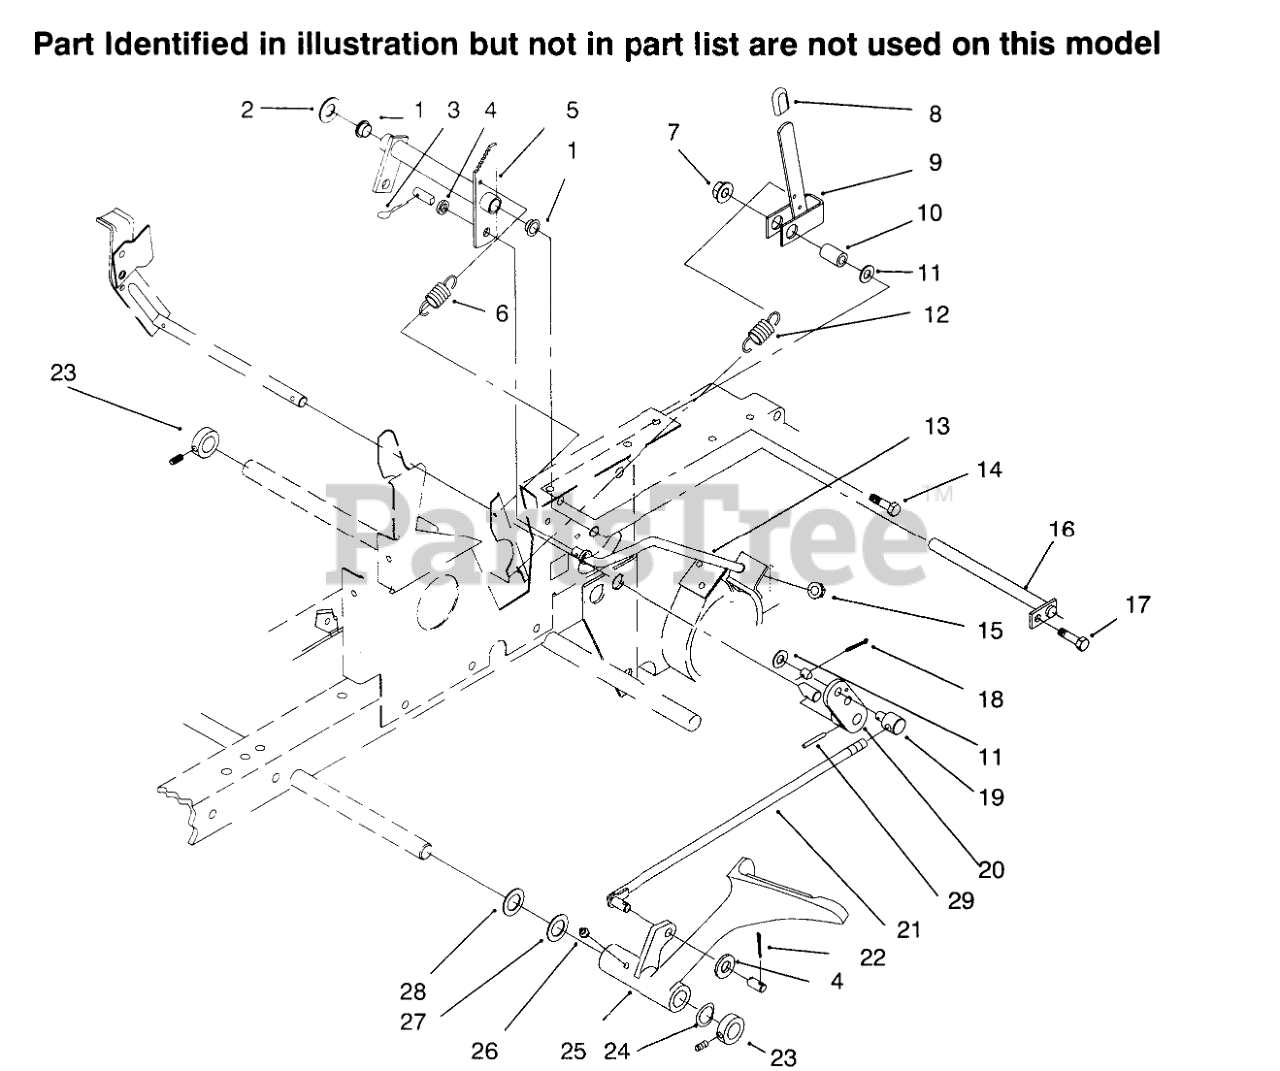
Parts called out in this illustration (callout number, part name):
1	BUSHING-FLANGED
2	WASHER-FLAT
3	PIN-HAIR
4	WASHER-NYLON
5	Bellcrank Assy
6	SPRING-EXTENSION
7	LOCKNUT-FLANGE
8	GRIP
9	ASSY-BRAKE LEVER WAB
10	SPACER
11	WASHER-FLAT
12	SPRING-BRAKE
13	ROD-REAR BRAKE
14	SCREW-HH
15	NUT-LOCK, NI
16	ROD ASM
17	Bolt
18	PIN-COTTER
19	TRUNNION
20	Arm-Clutch Rod
21	ROD AND GUIDE ASM
22	PIN-COTTER
23	COLLAR
24	WASHER-BOWED
25	Pedal-Clutch
26	FITTING-GREASE
27	WASHER
28	WASHER
29	PIN-SPIROL
30	SPRING-CLUTCH
